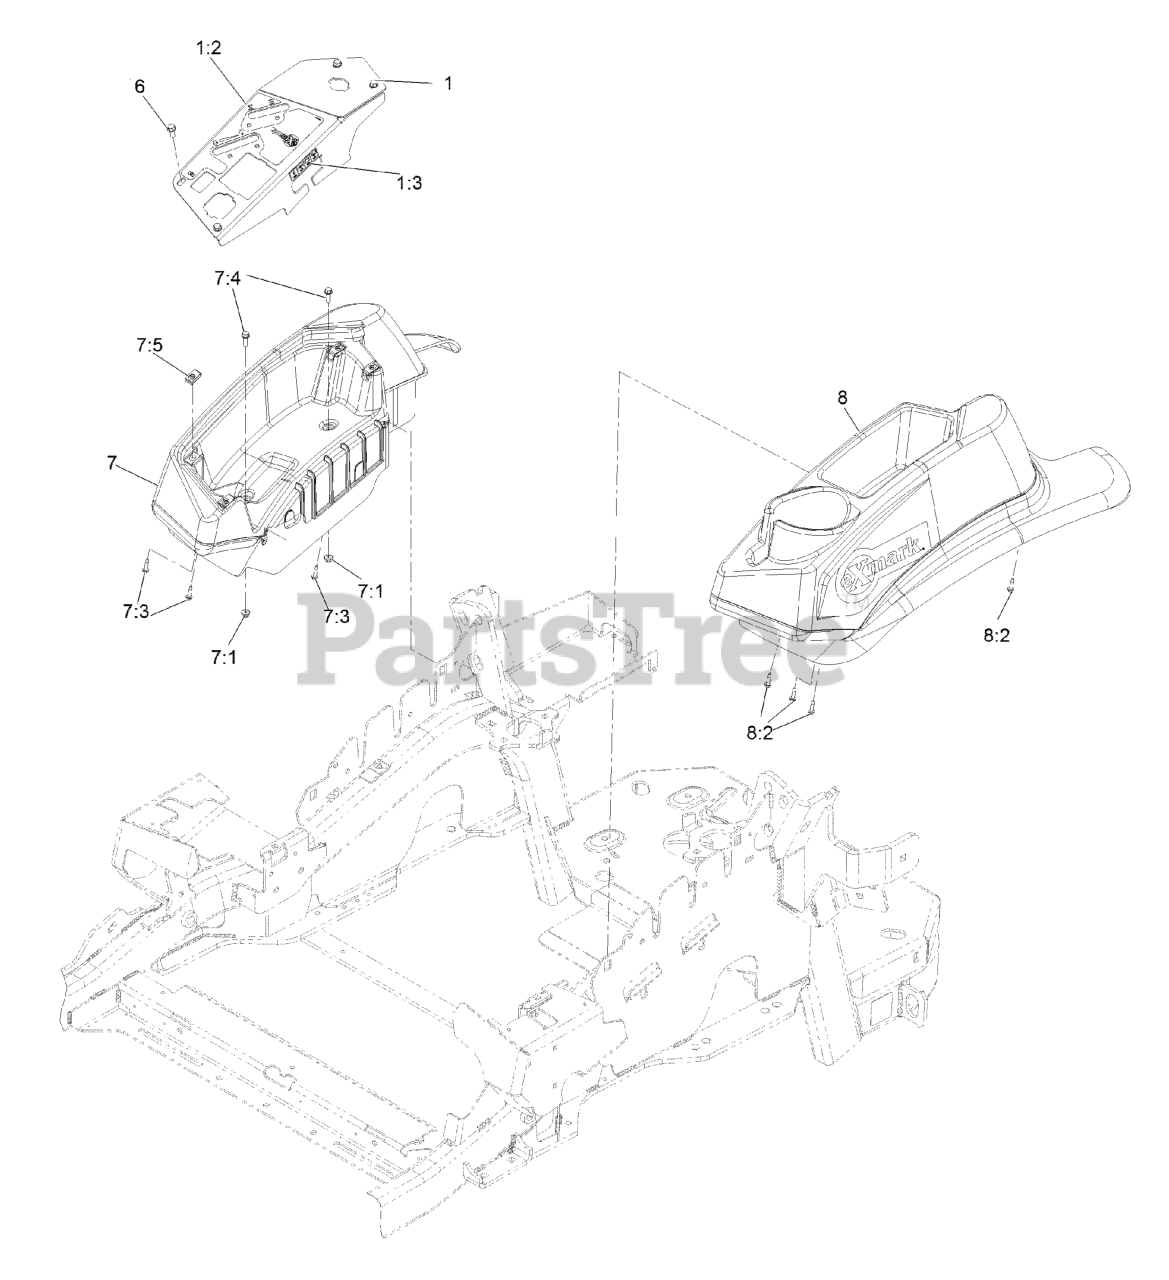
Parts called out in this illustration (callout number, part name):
1	ASM-PANEL, CONTROL W/DECAL
1:2	DECAL-CONTROL PANEL NON-EFI
1:3	DECAL-FUSES
6	SCREW-HWH
7	CONSOLE,RH NARROW ASM
7:3	SCREW,THD FORM,HWH
7:4	SCREW-HWH
8	CONSOLE.LH NARROW ASM
8:2	SCREW,THD FORM,HWH
